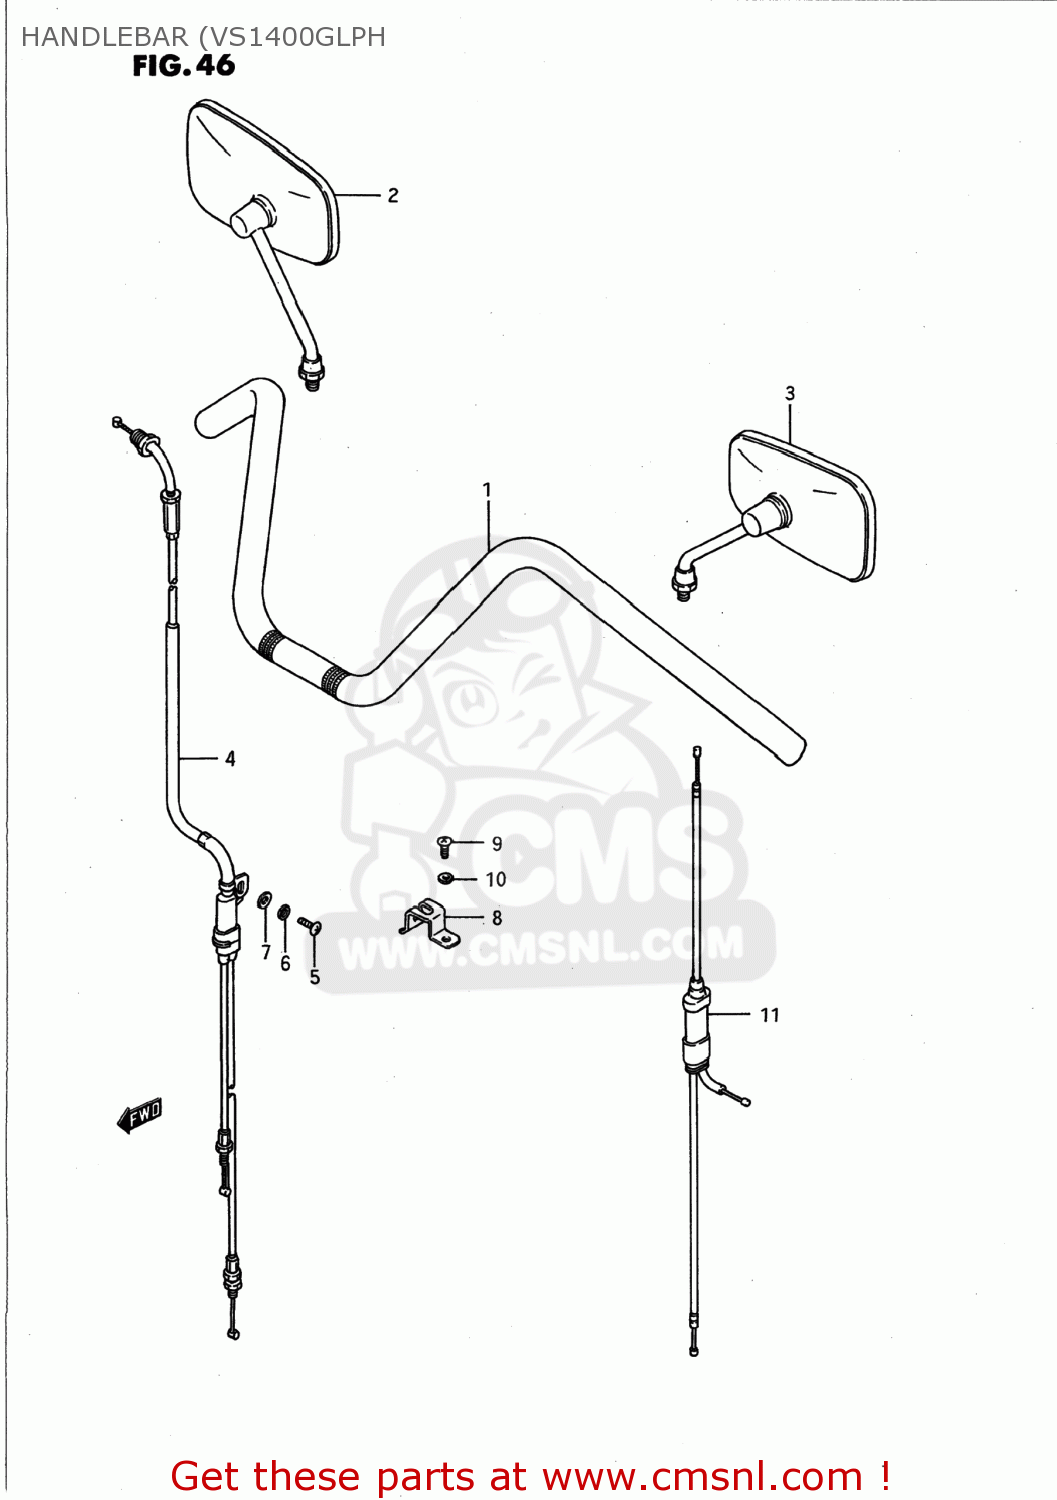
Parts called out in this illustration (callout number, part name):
1	HANDLEBAR,RIGHT
2	MIRROR ASSEMBLY,REAR VIEW
3	MIRROR ASSEMBLY,REAR VIEW
4	CABLE ASSEMBLY,THROTTLE
5	SCREW
6	LOCK WASHER
7	WASHER
8	CLAMP,THROTTLE CABLE CONNECTOR
9	SCREW
10	LOCK WASHER
11	CABLE ASSEMBLY,STARTER
